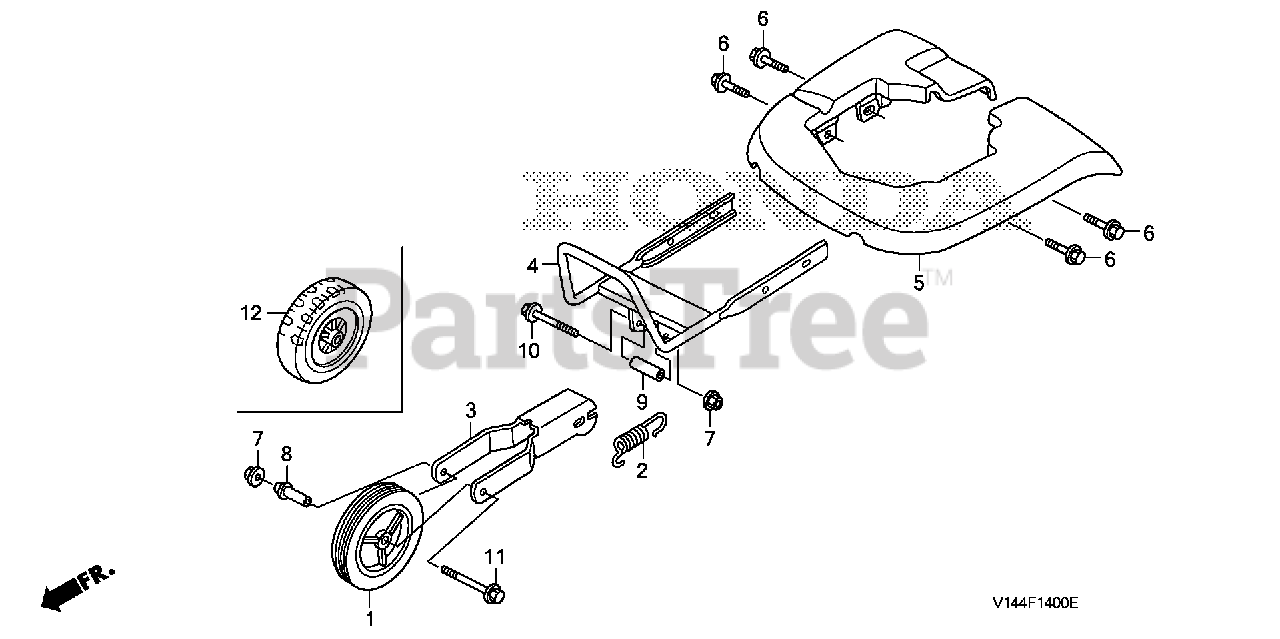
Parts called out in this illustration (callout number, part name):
1	WHEEL (7")
2	SPRING, RETURN
3	BEAM, FR. WHEEL
4	PIPE, FR. GUARD
5	FENDER, MAIN *R280* (POWER RED)
6	BOLT, FLANGE (6X20) (CT200)
7	NUT, FLANGE (8MM)
8	COLLAR, FR. WHEEL
9	COLLAR, ENGINE BED
10	BOLT, FLANGE (8X55)
11	BOLT, FLANGE (8X70)
